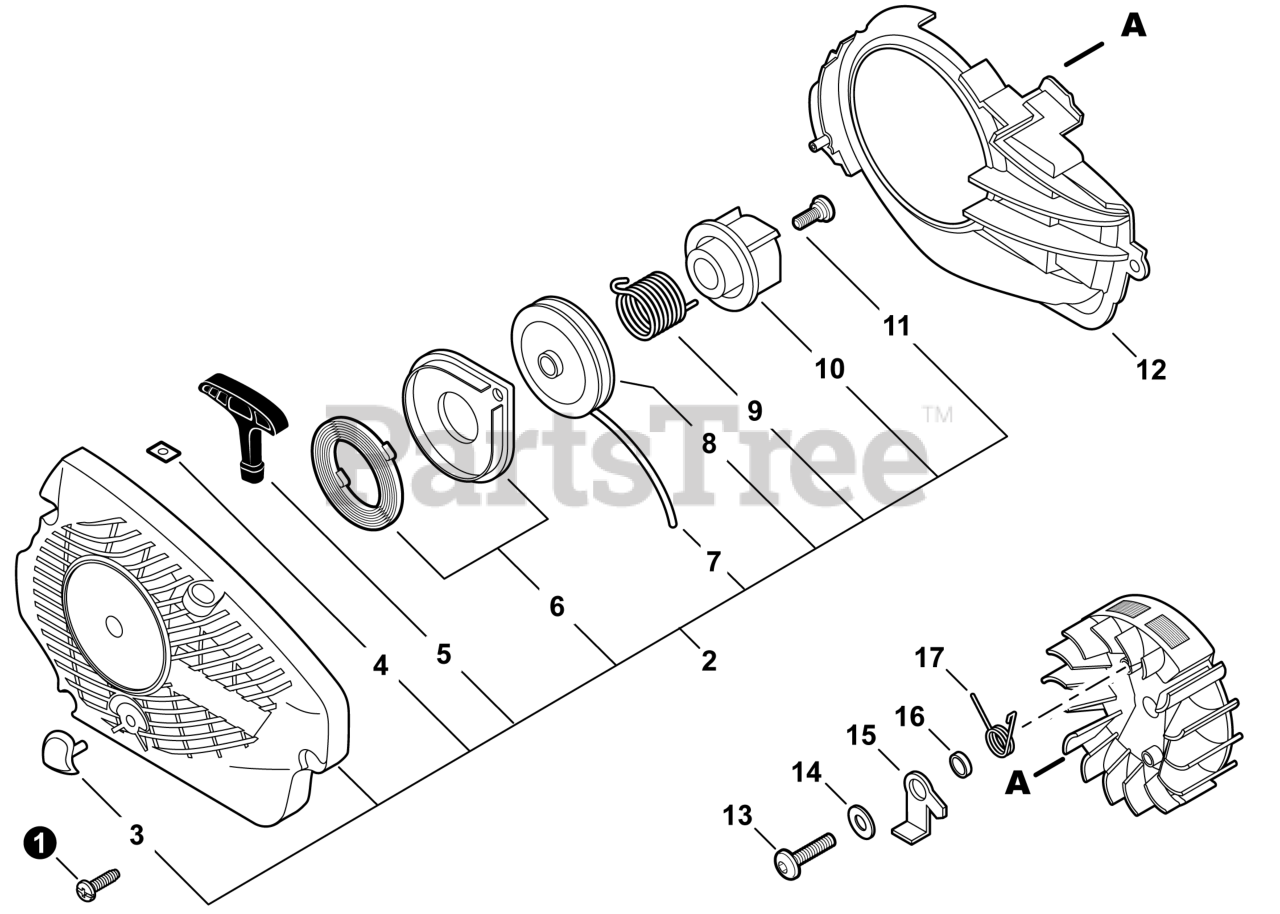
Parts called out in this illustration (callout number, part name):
1	SCREW 4x16
2	STARTER ASSY, RECOIL
3	PLUG
4	RETAINER, ROPE
5	GRIP, STARTER
6	SPRING KIT, RECOIL
7	ROPE, STARTER
8	REEL, ROPE
9	SPRING, TORSION
10	PAWL CATCHER
11	SCREW 5
12	COVER, FAN
13	BOLT 5x14
14	WASHER 5.5x12x0.8
16	SPACER 5.2x8x2.1
17	SPRING, TORSION
